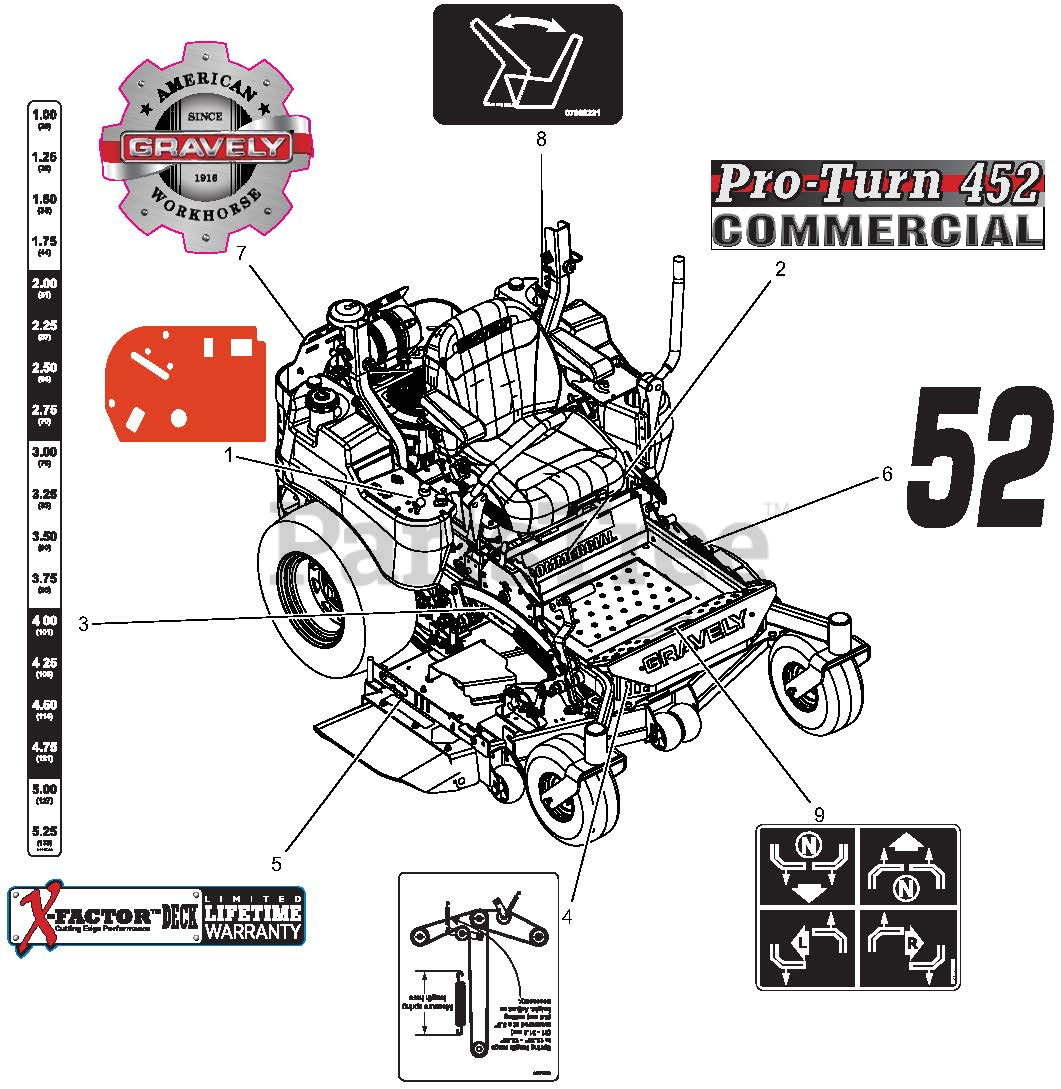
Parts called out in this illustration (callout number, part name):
1	DECAL, EFI CONTROL PANEL
2	DECAL, PT452
3	DECAL, PT400 HEIGHT OF CUT
4	DECAL, BELT ROUTING
5	DECAL, X-FACTOR DECK
6	DECAL, 52"
7	DECAL, GRAVELY HERITAGE-LARGE
8	DECAL, SEAT RELEASE
9	DECAL, INSTRUCTIONAL - STEERING
